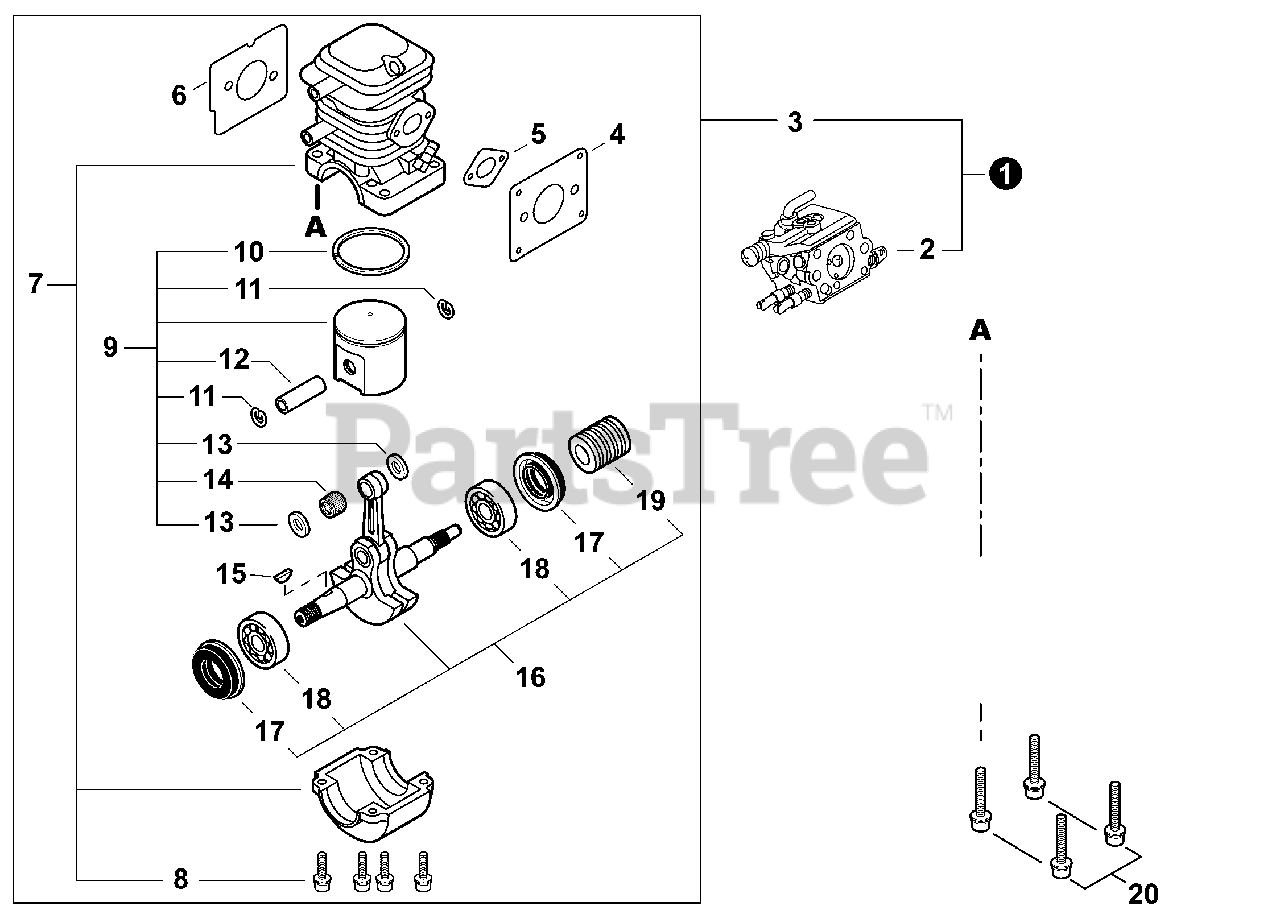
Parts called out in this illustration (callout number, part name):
1	SHORT BLOCK AND CARBURETOR WT-985
2	CARBURETOR WT-985
3	SHORT BLOCK
4	GASKET, INTAKE
5	GASKET, INTAKE
6	GASKET, EXHAUST
7	CRANKCASE KIT
8	BOLT 5×22
9	PISTON KIT
10	RING, PISTON
11	RING, SNAP
12	PIN, PISTON 9×6×33.8
13	WASHER, THRUST 9×12×15×3
14	BEARING, NEEDLE 9
15	KEY, WOODRUFF
16	CRANKSHAFT ASSY
17	SEAL, OIL 12
18	BEARING, BALL 6201
19	GEAR, WORM
20	BOLT 5×30
